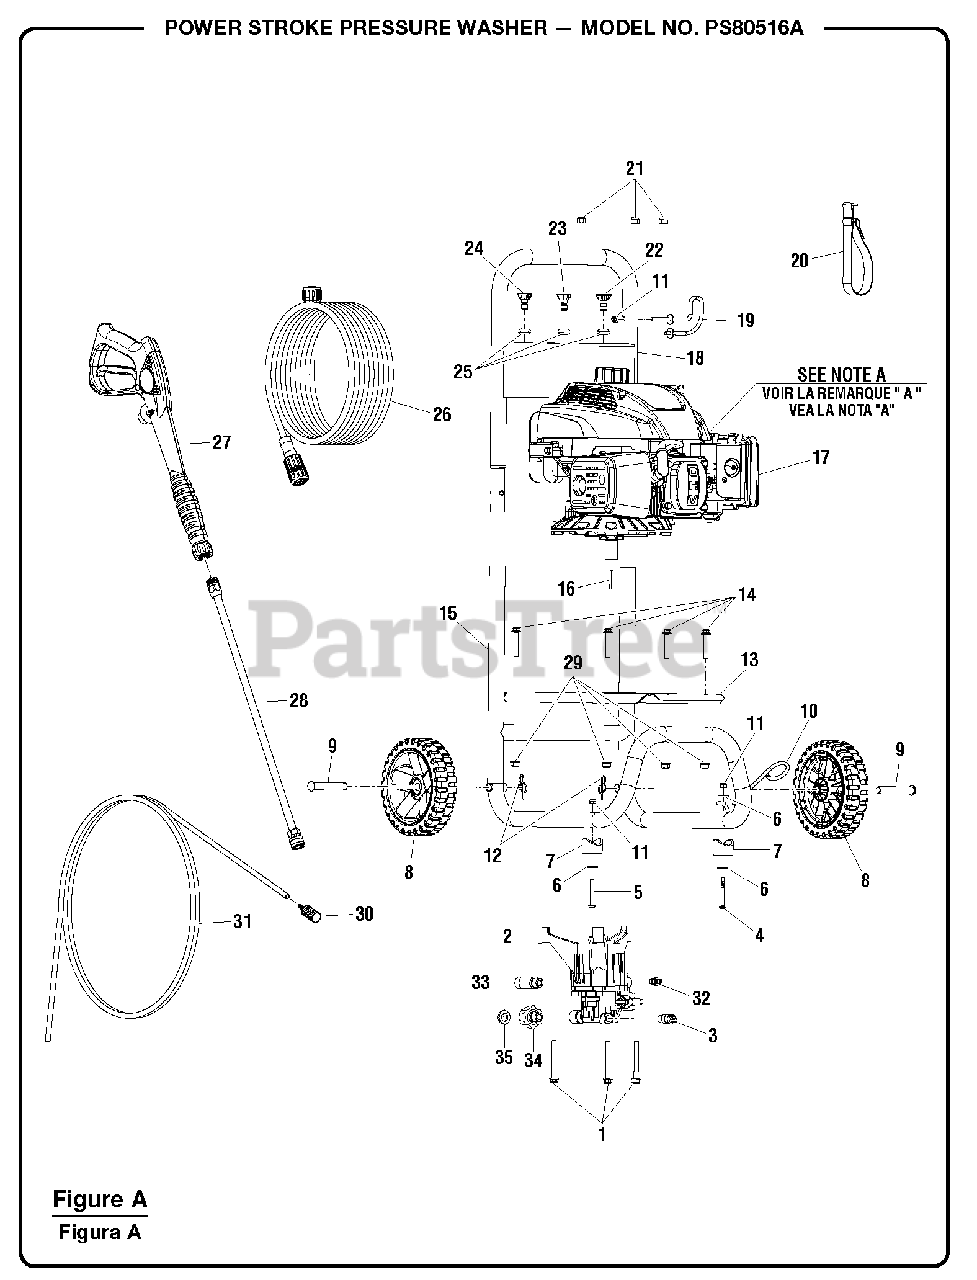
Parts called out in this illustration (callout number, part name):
1	Bolt (M8 x 70 mm, Flange Hd.)
3	Thermal Release Valve
4	Screw (1/4-20 x 2.2 in., Truss Hd.)
5	Screw (1/4-20 x 2 in., T30 Torx Hd.)
6	Washer (1/4 in.)
8	Wheel Assembly
10	Wand Holder
11	Lock Nut (1/4-20)
12	Hitch Pin
13	Engine Plate
14	Bolt (M8 x 45 mm, Flange Hd.)
15	Main Frame Assembly
16	Output Shaft Key
17	Engine (140 cc)
18	Handle Assembly
19	Wand Holder
20	Hose Storage Strap
21	Lock Nut (M8)
22	40deg Nozzle
23	25deg Nozzle
24	Soap Nozzle
25	Nozzle Holder
26	25 ft. Hose
27	Trigger Handle
28	Extension Wand
29	Lock Nut (M8)
30	Chemical Siphon Filter
31	Chemical Siphon Tube
32	Thermal Release Valve
33	Outlet Tube
34	Inlet Tube
35	Filter Screen
